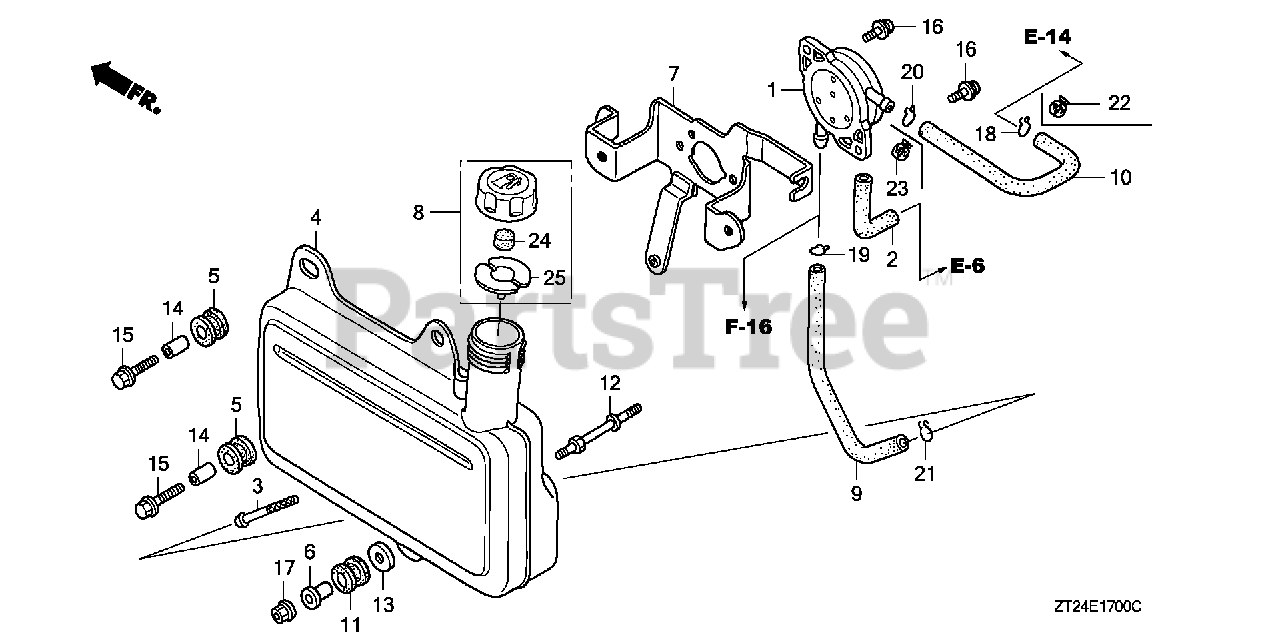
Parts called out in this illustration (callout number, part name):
1	PUMP ASSY., FUEL
2	TUBE, DIAPHRAGM
3	FILTER, FUEL
4	TANK, FUEL
5	RUBBER B, TANK MOUNTING
6	COLLAR, FUEL TANK SETTING
7	STAY A, FUEL TANK
8	CAP ASSY., FUEL TANK
9	TUBE, FUEL TANK
10	TUBE, FUEL
11	CUSHION, RR. FENDER
12	BOLT, FUEL TANK STUD (H=30MM)
13	WASHER (6MM)
14	COLLAR (14X6.1)
15	BOLT-WASHER (6X25)
16	SCREW-WASHER (5X14)
17	NUT, FLANGE (6MM)
18	CLIP, TUBE (B8)
19	CLIP, TUBE (B10)
20	CLIP, TUBE (C9)
21	CLIP, TUBE (C11)
24	SPONGE, FUEL CAP BREATHER
25	GASKET, FUEL CAP
